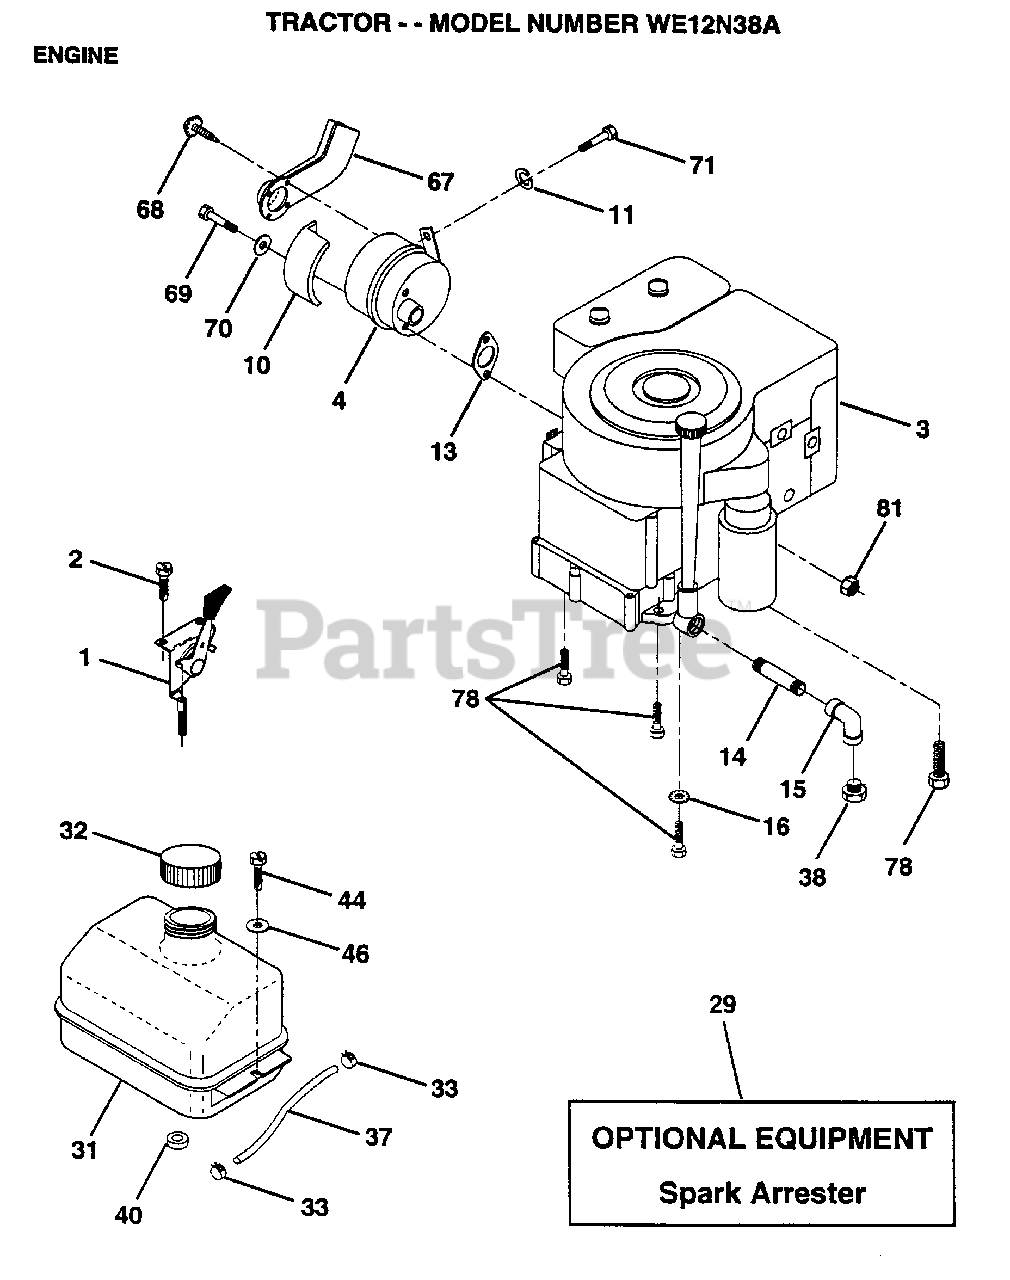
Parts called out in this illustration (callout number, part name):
1	THROTTLE CONTROL
2	SCREW LT
3	ENG B&S 10-12.5HP PWRBLT DC
4	MUFFLER LTV
10	SHIELD HEAT LTV
11	LOCKWASHER
14	PIPE NIPPLE
15	ELBOW
16	LOCKWASHER
31	TANK.FUEL.LT.
32	CAP ASM FUEL
33	HOSE CLAMP
37	LINE FUEL
45	SCREW HEX CRT
46	WASHER
67	DEFLECTOR MUFFLER
69	"BOLT,HEX"
70	WASHER T
71	BOLT HXHD FIN
78	SCREW
81	NUT
